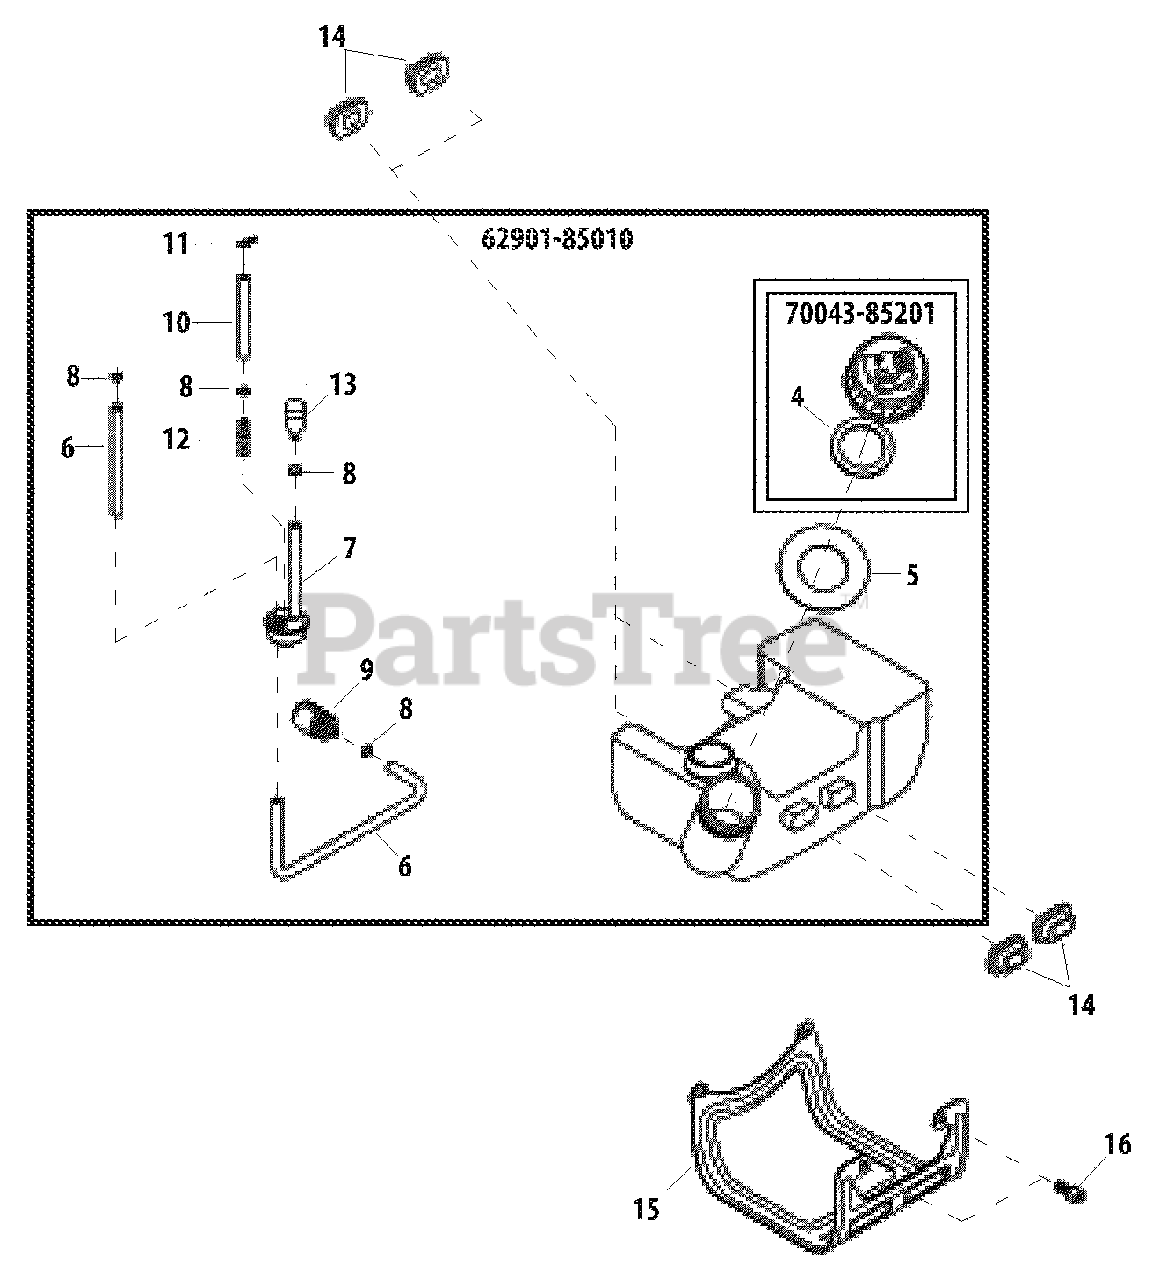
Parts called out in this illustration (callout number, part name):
4	GASKET, FUEL CAP
5	PLATE, CAUTION
6	PIPE, FUEL 3.3×6×160
7	GROMMET
8	CLIP Ø6
9	FILTER, FUEL 125-528
10	PIPE, FUEL RETURN
11	CLIP, SPRING Ø5.2
12	CONNECTOR, PIPE
13	VENT ASSY
14	CUSHION, FUEL TANK
15	GUARD, METAL FUEL TANK
16	BOLT 5×8
62901-85010	FUEL TANK ASSY
70043-85201	CAP ASSY, FUEL
